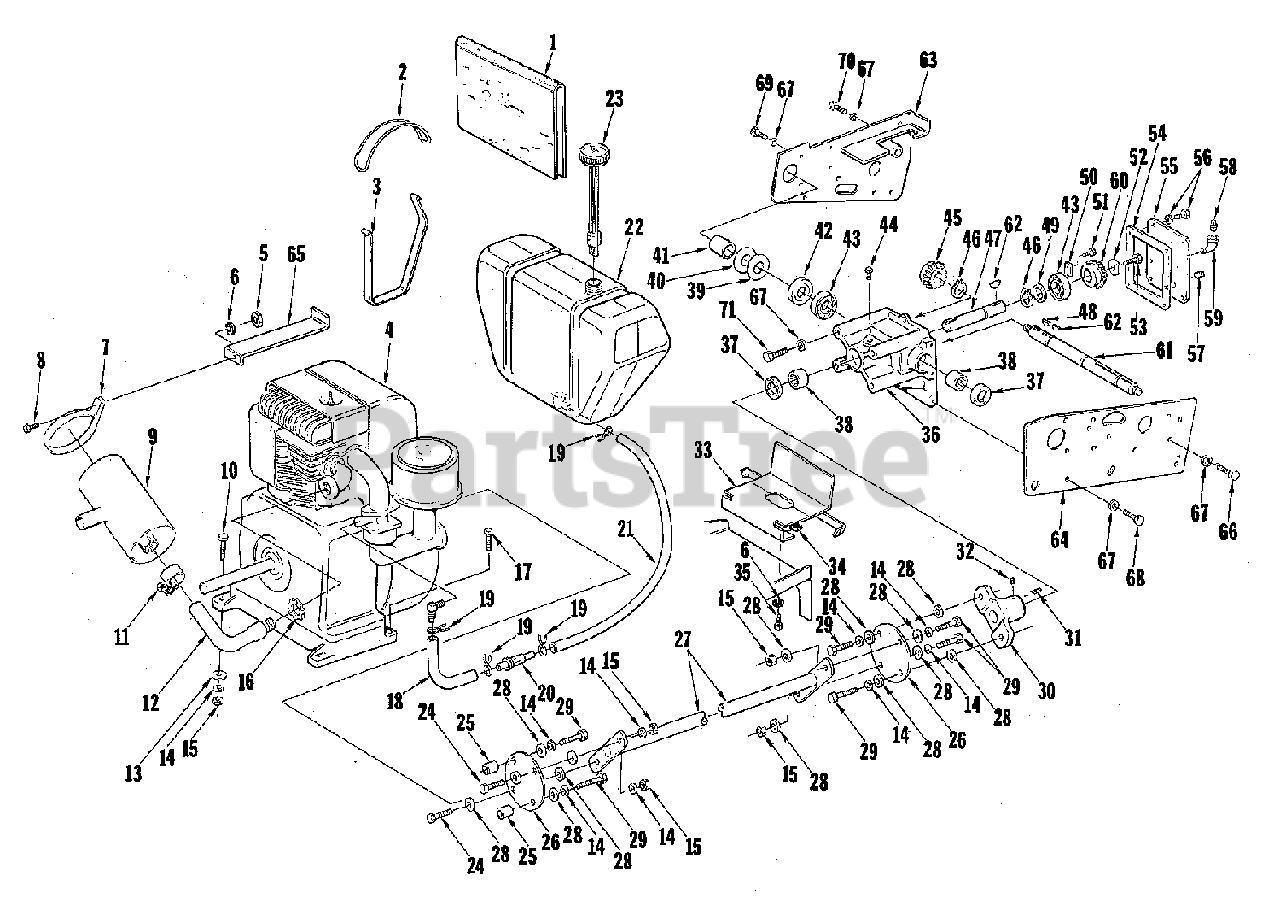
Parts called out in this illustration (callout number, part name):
1	INSULATION, Fuel Tank
2	STRAP, Fuel Tank
3	STRAP, Fuel Tank
4	ENGINE, T-10 HP
4	ENGINE, T-12 HP
4	ENGINE, T-15 HP
5	NUT, Hex, 5/16-18
6	WASHER, Lock, 5/16
7	STRAP, Muffler
8	SCREW, Hex Head Cap, 5/16-18 x 1
9	MUFFLER, Exhaust
10	SCREW, Hex Head Cap, 3/8-16 x 1-1/2
11	CLAMP, Muffler w/Fasteners
12	ELBOW & NIPPLE ASSEMBLY
14	WASHER, Lock, 3/8
15	NUT, Hex Fin, 3/8-16
17	SCREW, Rectangle Head, 3/8-16 x 1-5/16
20	FILTER, Fuel
23	CAP, Fuel Tank w/Guage
24	SCREW, Hex Head Cap, 3/8-16 x 1-1/2
25	SPACER, Drive Shaft
26	COUPLING, Drive Shaft
27	SHAFT ASSEMBLY, Drive
28	WASHER, Special
29	SCREW, Hex Head Cap, 3/8-16 x 1-1/4
30	FLANGE, Drive Shaft
31	KEY, Parallel, Special
32	SETSCREW, Hex Socket, 3/8-24 x 5/16
33	SUPPORT ASSEMBLY, Fuel Tank
34	NUTSERT, Fastener
35	SCREW, Hex Head Cap, 5/16-18 x 3/4
36	HOUSING, Bevel Gear
38	BEARING, Needle
41	SPACER, (T-10)
41	SPACER, (T-12, T-15)
43	BEARING, Ball
45	GEAR, Bevel Driven
46	RING, Retaining
47	SHAFT, Driven (T-10)
47	SHAFT, Driven (T-12, T-15)
48	KEY, Hi-Pro (T-12, T-15)
48	KEY, #9 (T-10)
50	PLATE, Bearing Clamp
53	SCREW, Hex head Cap, 5/16-18 x 3/4
55	COVER, Housing
56	SCREW, Cap w/Internal Tooth Washer, 1/4-20 x 5/8
57	PLUG, Pipe, 1/4
58	PLUG, Pipe, 3/8
59	ELBOW, Street, 3/8 x 90 Degrees
60	GEAR, Bevel Driver
61	SHAFT, Driver
62	KEY, Woodruff
63	PLATE, Side, R.H. (T-10)
63	PLATE, Side, R.H. (T-12, T-15)
64	PLATE, Side, L.H. (T-10)
64	PLATE, Side, L.H. (T-12, T-15)
65	BRACKET, Voltage Regulator
66	SCREW, Hex Head Cap, 7/16-14 x 1-1/4 (T-10)
67	WASHER, Lock
68	SCREW, Hex Head Cap (T-10)
69	SCREW, Hex Head Cap, 7/16-14 x 1 (T-10)
69	SCREW, Hex Head Cap (T-12, T-15)
70	SCREW, Hex Head Cap, (T-10)
70	SCREW, Hex Head Cap, (T-12, T-15)
71	SCREW, Hex Head Cap
72	NUT, Hex, 7/16-14 (T-12, T-15)
